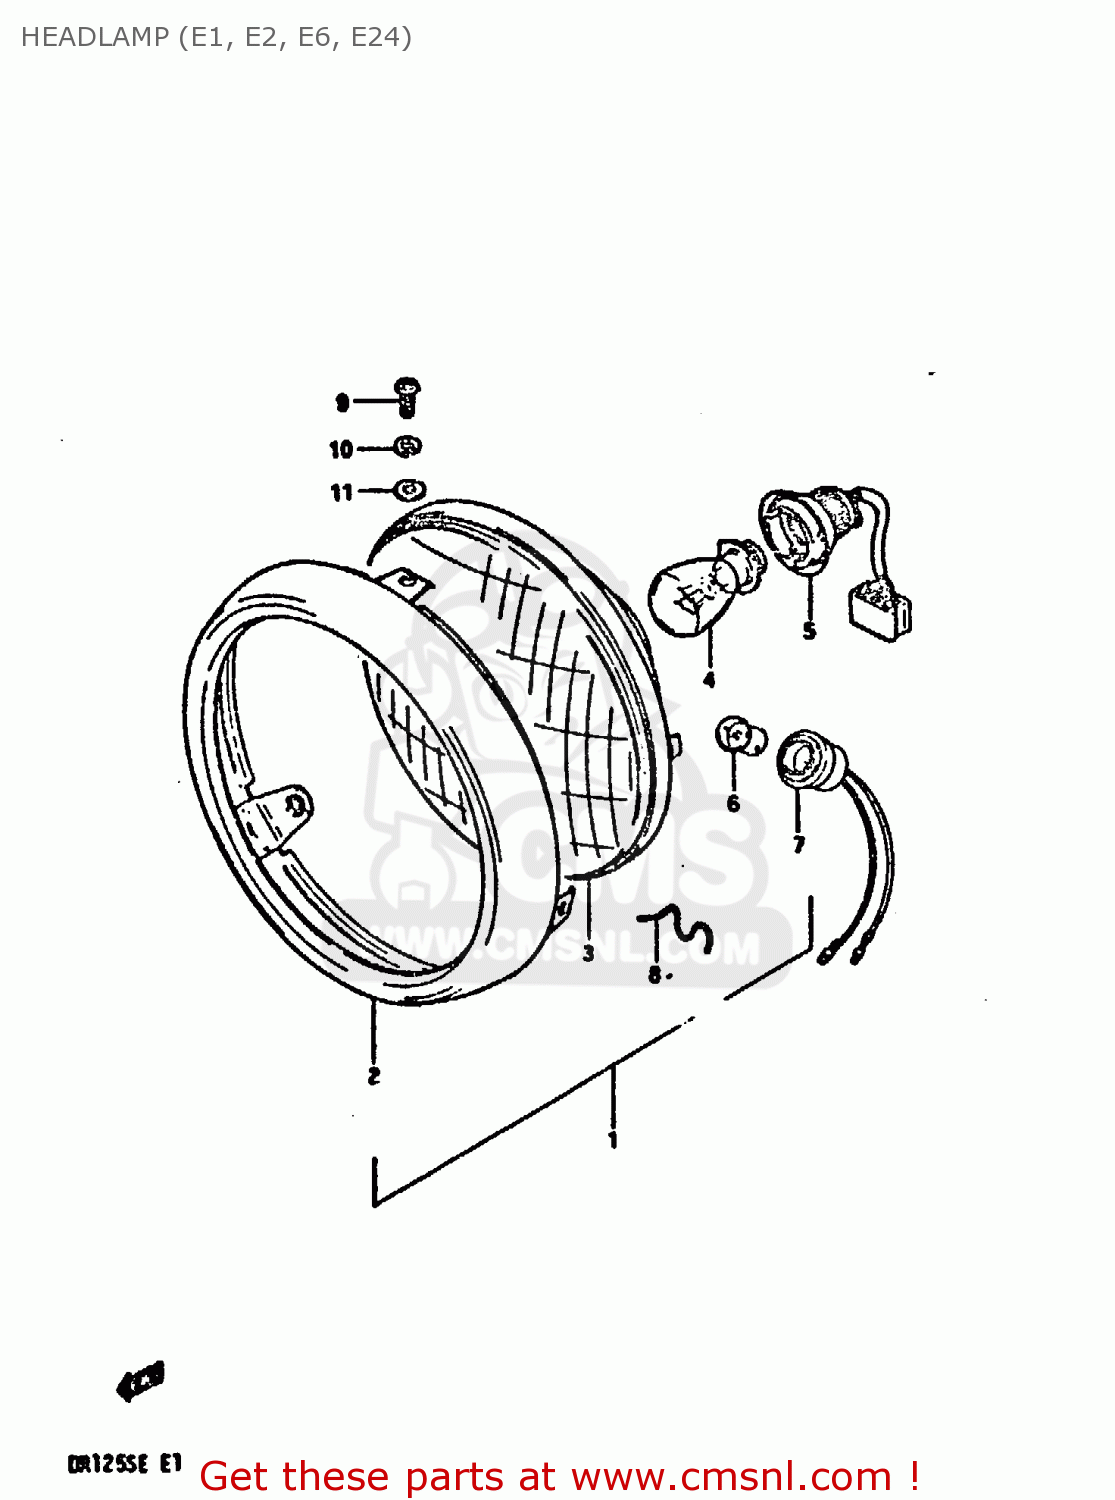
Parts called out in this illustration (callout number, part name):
1	HEADLAMP ASSY
2	RIM
3	UINT
4	BULB
5	SOCKET
6	BULB(6V/3W)
7	SOCKET
8	SPRING
9	SCREW
10	LOCK WASHER
11	WASHER
